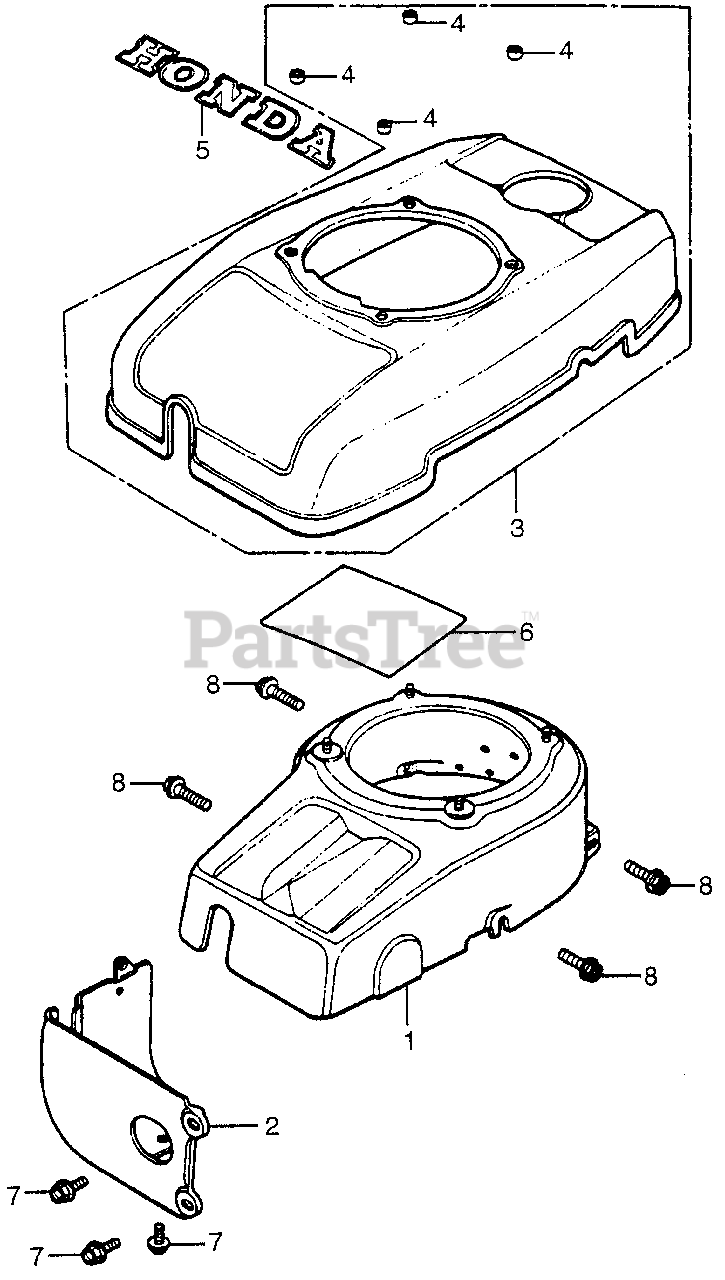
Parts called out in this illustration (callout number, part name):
1	COVER, FAN *A14* (SNAPPER WHITE)
2	COVER, SIDE
3	COVER, TOP *R8* (BRIGHT RED)
6	PLATE, DESCRIPTION
7	BOLT, FLANGE (6X12)
8	BOLT, FLANGE (6X16)
